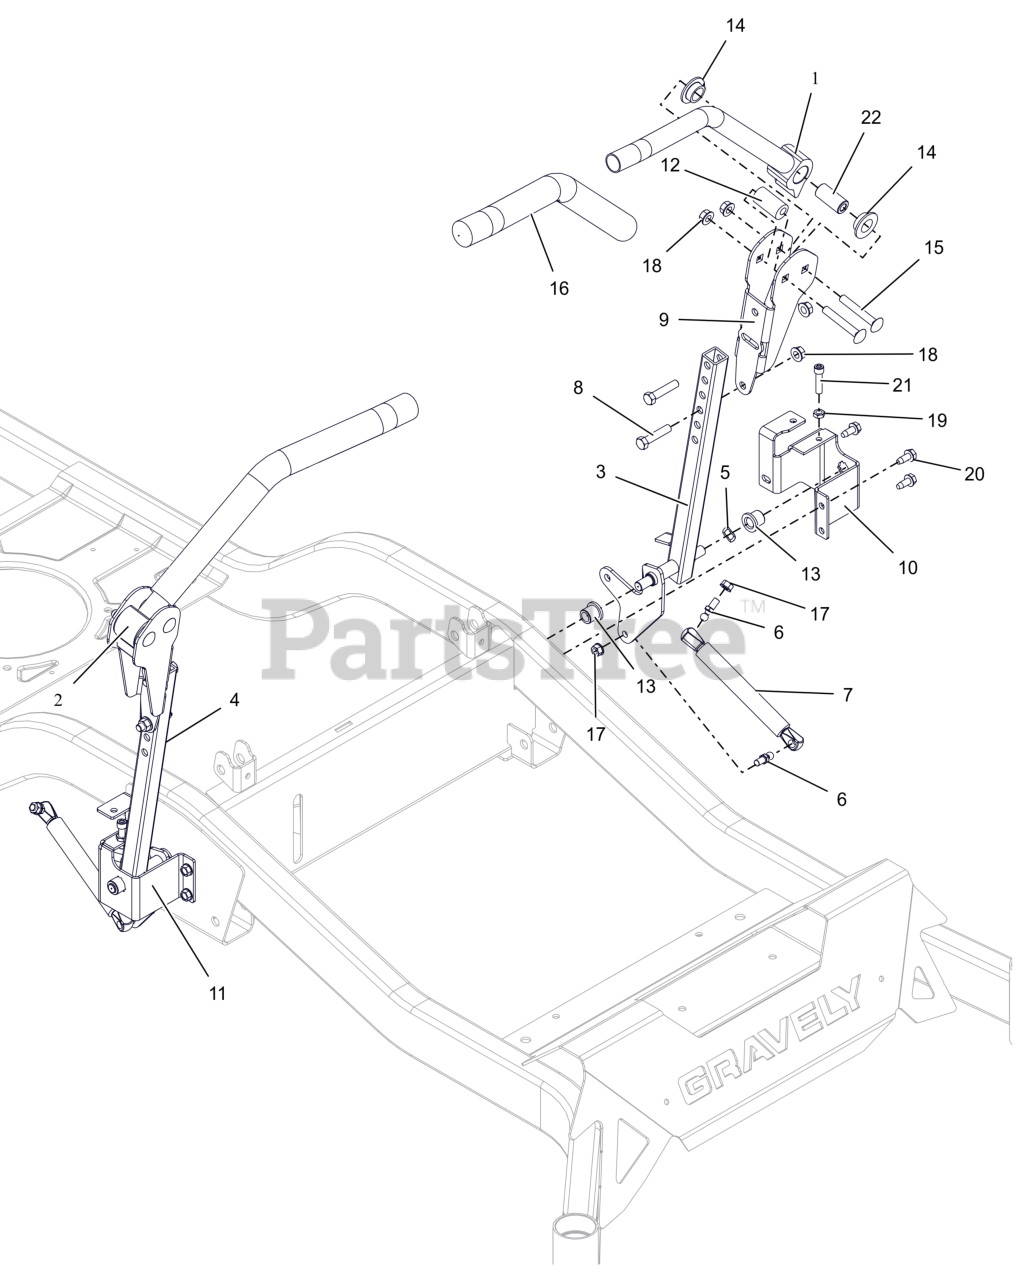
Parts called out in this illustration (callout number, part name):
1	WLDMT, CONTROL HANDLE-LH
2	WLDMT, CONTROL HANDLE-RH
3	WLDMT, STEERING -LH (BLACK)
4	WLDMT, STEERING RH (BLACK)
5	WAVE WASHER .531X.781X.125FH
6	STUD- BALL
7	DAMPER
8	BLT, HEX .38-16X1.75 G5 ZCC
9	ADJ UPPER CONTROL ARM BRKT-BLK
10	BRKT, STEERING ARM MOUNT -LH
11	BRKT, STEERING ARM MOUNT -RH
12	BSHG, ECCENTRIC.406X.875X1.625
13	BHSG-FLG .500X.750X.750X.125
14	BSHG-FLG .762X1.48X.44 NYL
15	BLT, RHSSN.38-16X2.50 G5 ZCC
16	GRIP, HANDLEBAR
17	NUT,LK-CTR-FLG .31-18 GF ZCC
18	NUT-LK-TOP-FLG .38-16 ZC120
19	NUT-JAM .312-18 G2 ZCC
20	SCR,TAP .312-18X.75 HWH TR ZCC
21	SCR, SKH .312-18X1.25 GR8 ZC120
22	SPACER, STEERING ARM
